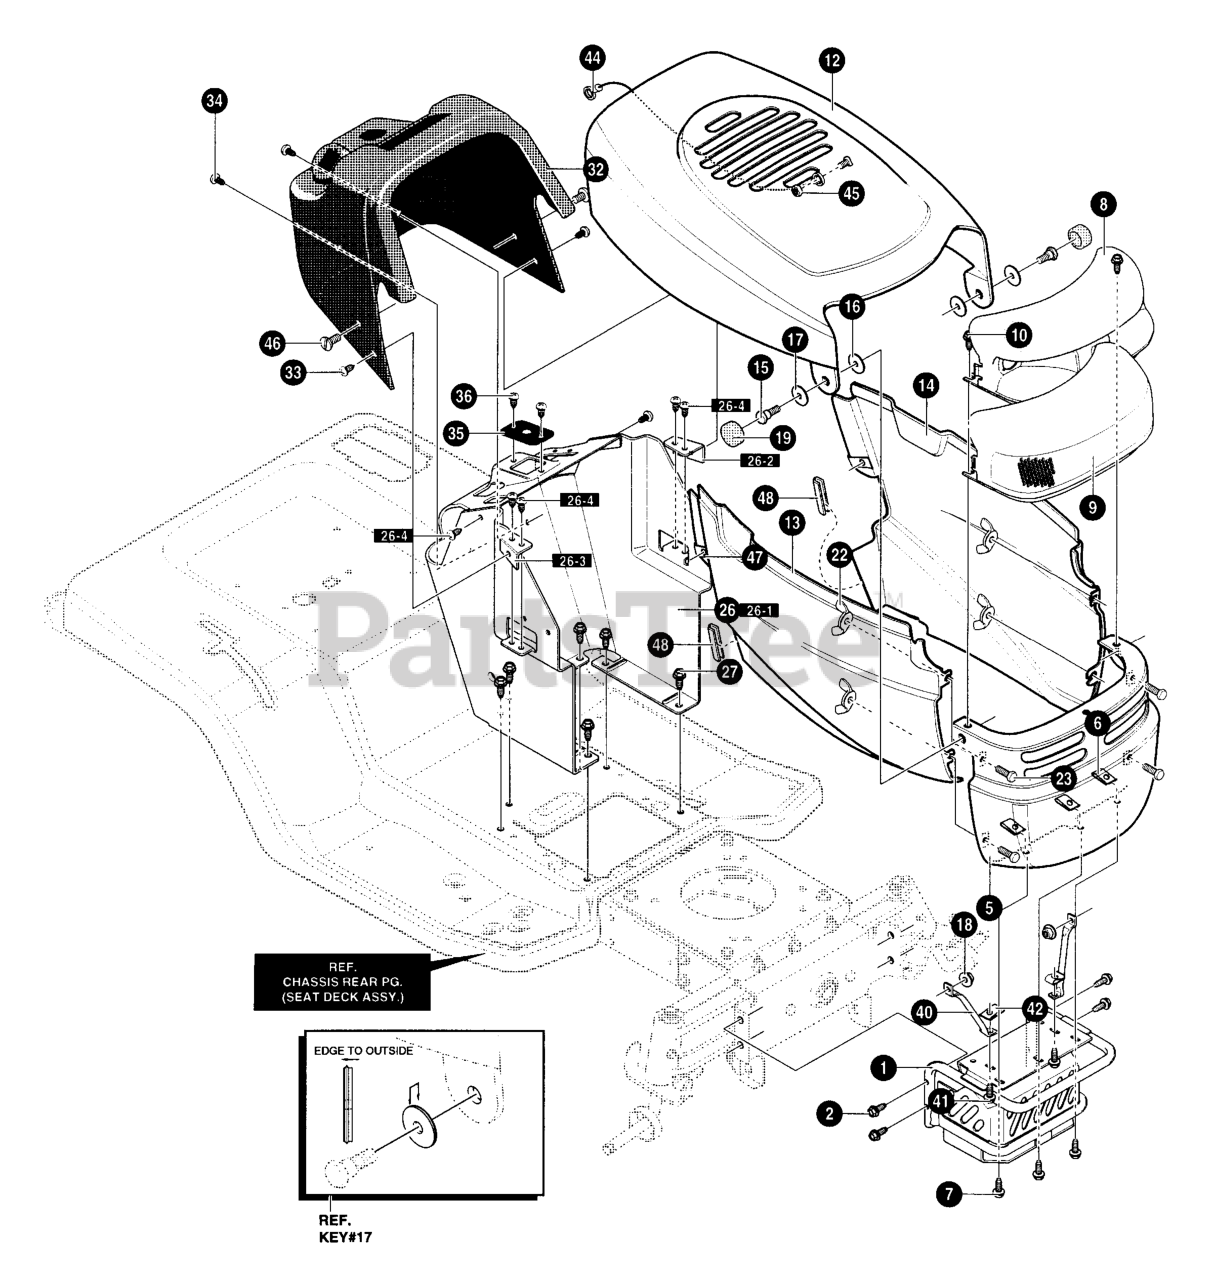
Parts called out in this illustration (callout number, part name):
1	BUMP/GRIL MNT
2	SCREW 5/16- 18X1.38
6	NUT, "J" TINNERMAN
7	SCREW 1/4-20X.63
8	REFLECTOR
10	SCREW, 1/4- 14X.50
12	ASSEMBLY, HOOD
13	PANEL, SIDE RH
14	PANEL, SIDE LH
16	WASHER, PLASTIC
17	PIVOT BASE
18	NUT, 3/8- 16
19	CAP, PIVOT
22	NUT, WING 1/4-20
23	SCREW 1/4-20X1.25
26	CONSOLE ASSY
26-1	CONSOLE, DASH
26-2	BRACKET, LH
26-3	BRACKET, RH
26-4	SCREW, 10- 24X.5
27	SCREW 5/16- 18
33	SCREW 10- 24X.5
34	SCREW 10- 24X.5
35	STEERING BEARING
36	SCREW, 1/4- 14X.5
40	STRUT, GRILLE
41	SCREW 1/4-20X.63
42	SPEED NUT
44	LANYARD, HOOD
45	NUT, 1/4-20
46	SCREW 1/4-20X.63
47	NUT, "J" TINNERMAN
48	TRIM
